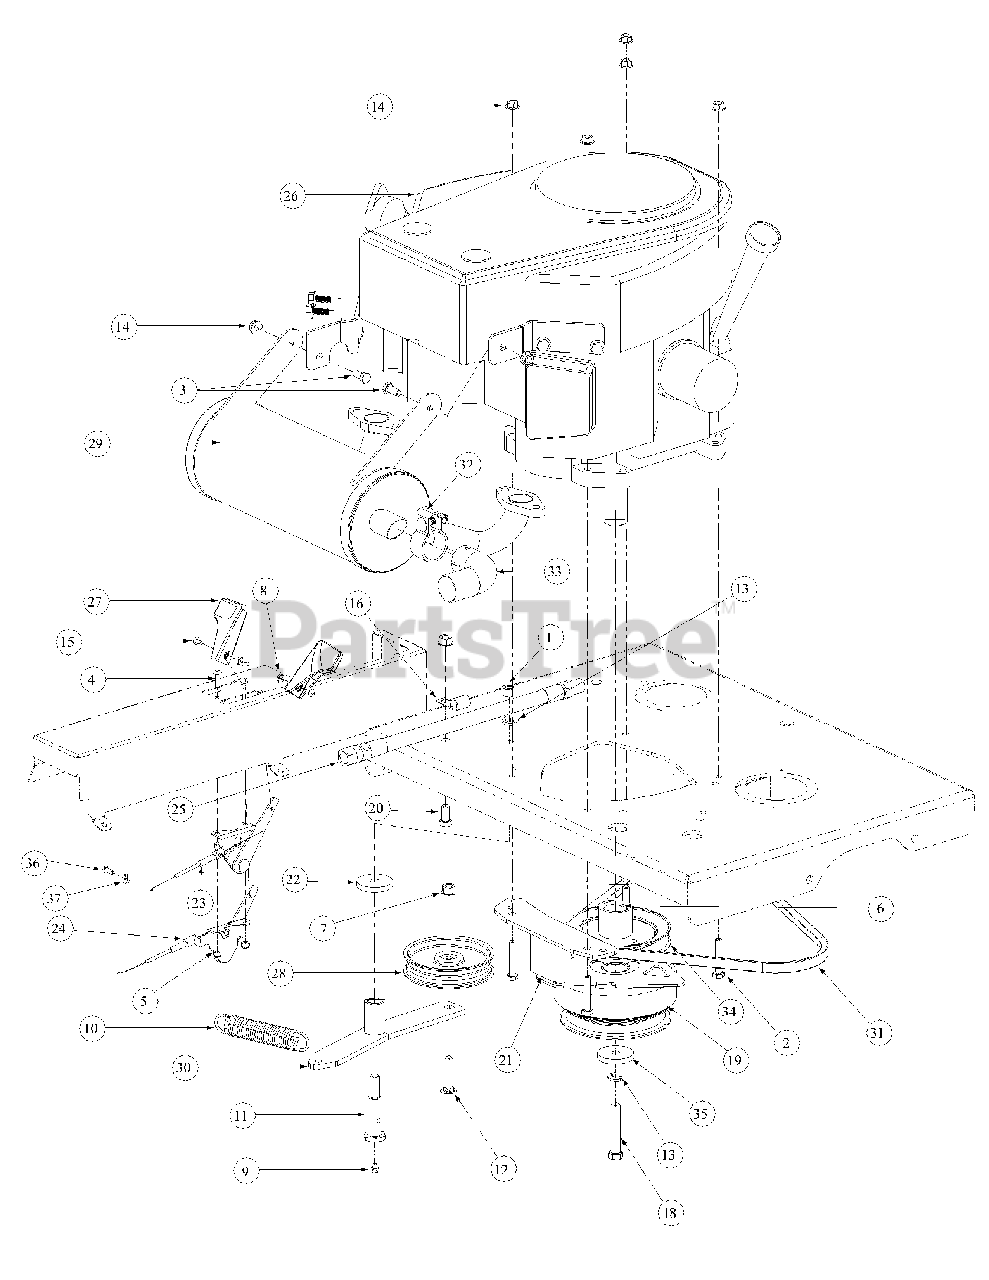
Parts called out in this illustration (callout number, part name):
1	Hex Nut, 7/16-14
2	HHCS, 5/16-18, 1-3/4
3	Hex Cap Screw, 5/16-18 x 3/4
4	Round Hd. Machine Screw, 10-32 x 3/4
5	Lock Nut, Nylon Insert, 10-32
6	Key, 1/4 x 1/4 x 3
7	Flange Lock, Hex Nut, 3/8-16
8	Nut Washer, W/Star, 8-32
9	Grease Fitting, 1/4-28 x 3/16
10	Extension Spring, 1.0 OD x 5.125
11	Shoulder Screw, 7/16-14
12	Hex Carriage Screw, 3/8-16, 1.75
13	Lock Washer, 7/16
14	Hexflange Lock Nut, 5/16-18
15	Machine Screw, 8-32, .375
16	Clip, Heat Shield Cable
17	Hex Cap Screw, M*-1.25 x 20mm
18	Capscrew, 7/16-20 x 2.50
19	Clutch Brake, 1.125 ID
20	Hex Cap Screw, 3/8-16, .750
21	Retainer Clutch Assembly, Ogura
22	Flat Washer, 7/16 ID x 1.75 OD x .25
23	Choke, Control Cable, 43.0
24	Throttle, Control Cable, 39.0
25	Oil Drain Hose
26	19HP Twin Engine, Kawasaki
26	23HP Kawasaki Engine
27	Control Throttle Knob
28	Flat Pulley with Flanges
29	Muffler Accessory, Kawasaki
30	Engine Idler Arm Assembly
30	Bearing
31	V Belt, A Section x .47.3
31	Belt: For New Sub-Frame
32	Tube Clamp, 1.375
33	Muffler Accessory Exhaust Tube
34	Pump Drive Pulley
35	Flat Washer, 7/16 ID x 1.75 OD x .25
36	Bolt, M5 x 18
37	Choke Cable Clamp
